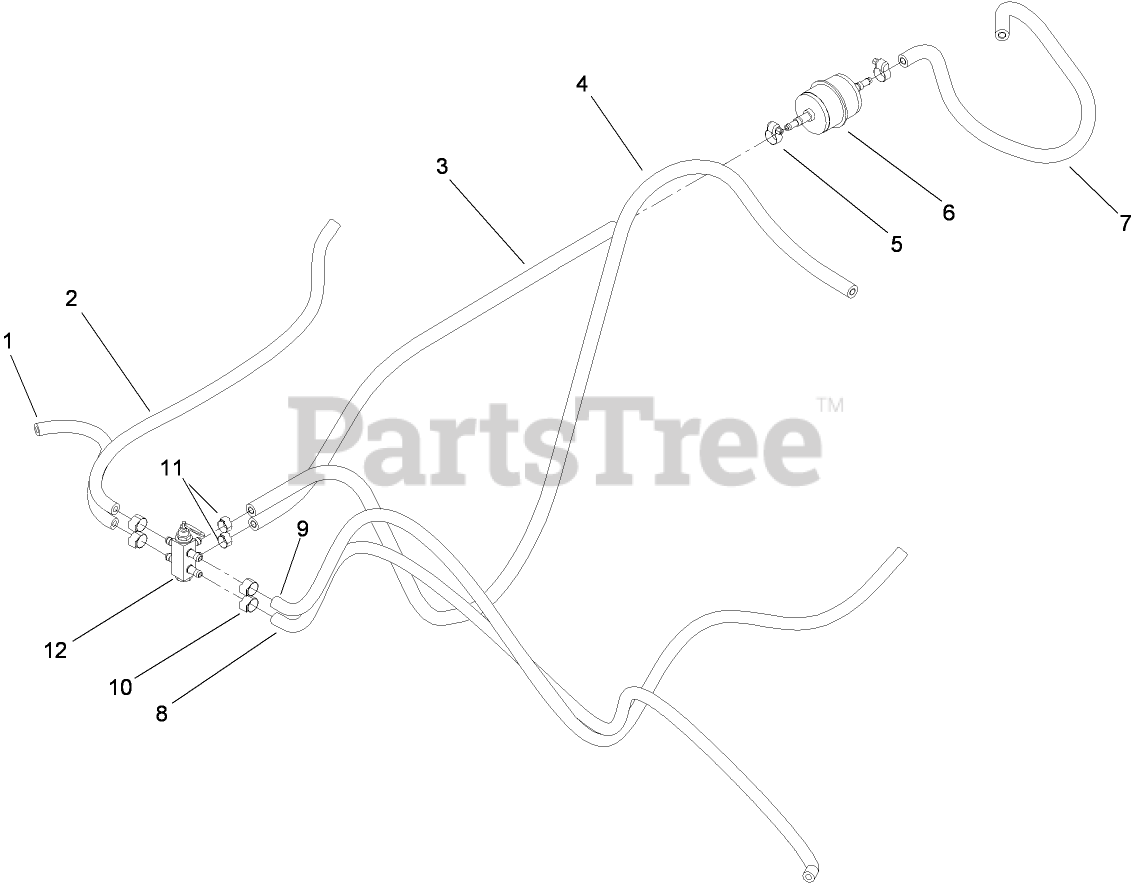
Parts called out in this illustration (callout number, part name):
1	Hose-Fuel
2	HOSE-FUEL
3	HOSE-FUEL
4	HOSE-FUEL
5	CLAMP-WORM
6	FILTER-INLINE
7	HOSE-FUEL
8	HOSE-FUEL
9	HOSE-FUEL
10	CLAMP-HOSE, FUEL
11	CLAMP-HOSE, FUEL
12	VALVE-FUEL, DUAL FLOW
